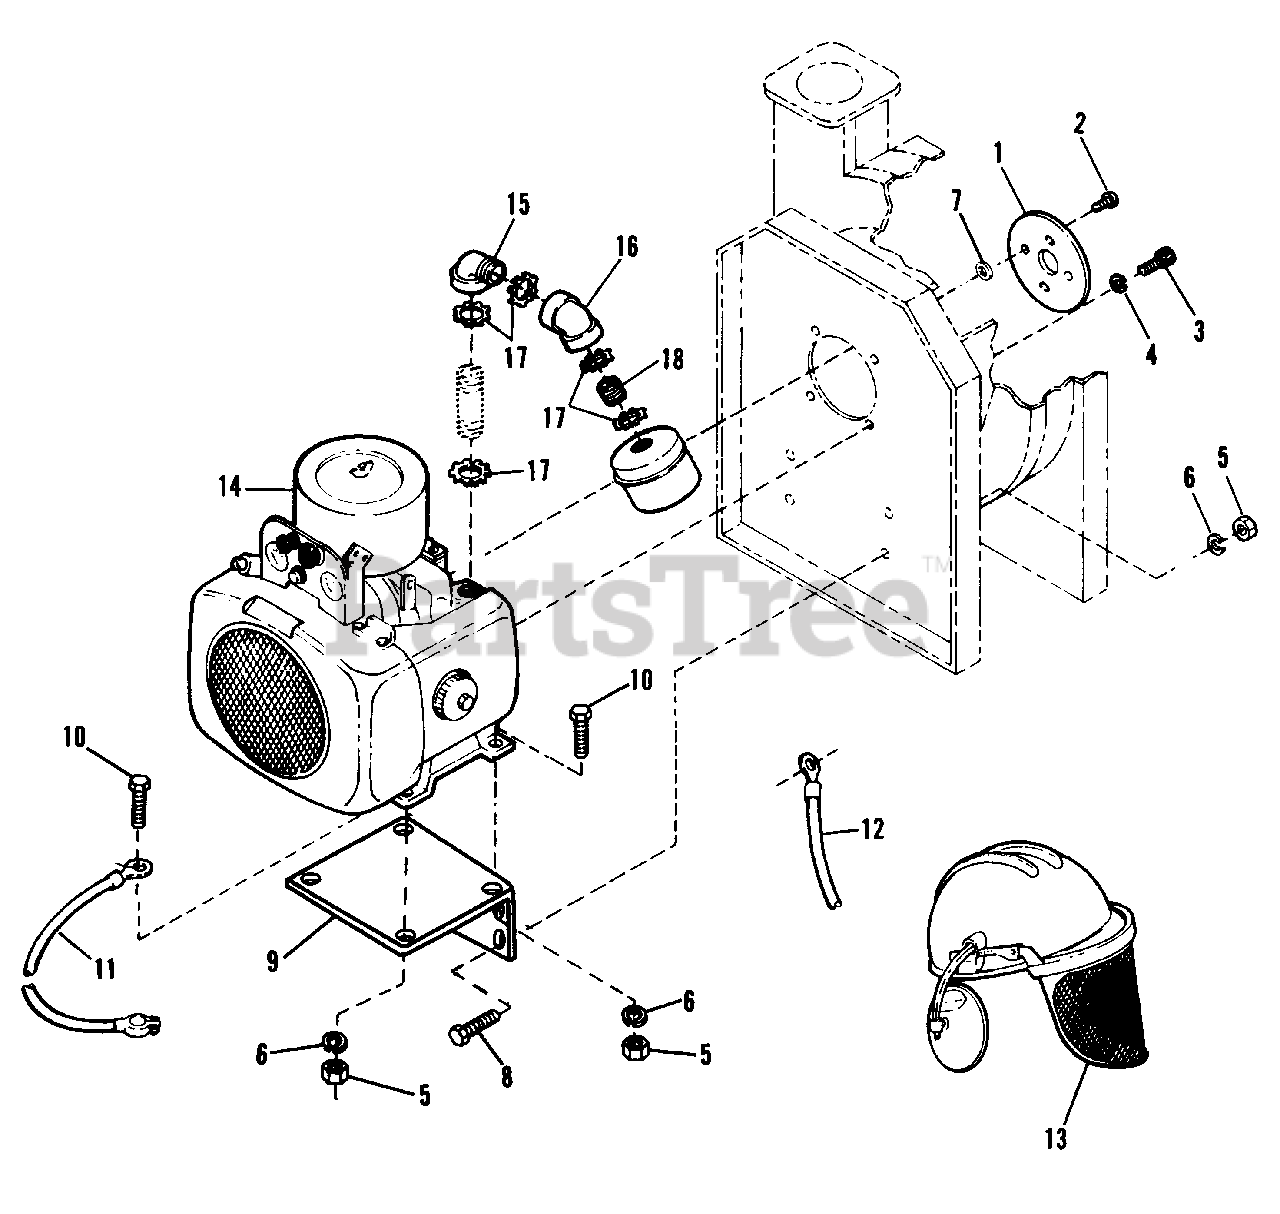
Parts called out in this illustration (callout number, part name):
1	GUARD, Seal
2	SCREW, Button Socket Hd., 3/8-16 x 3/4
3	CAPSCREW, Hex, 3/8-16 x 1-3/4
4	LOCKWASHER, 3/8
5	NUT, Hex, 7/16-14
6	LOCKWASHER, 7/16
7	WASHER, Plain, 13/32 x 7/8 x 5/64
8	CAPSCREW, Hex, 7/16-14 x 1
9	SUPPORT ASSY., Engine
10	CAPSCREW, Hex, 7/16-14 x 1-1/4
11	CABLE, Battery, Black, 30"
12	CABLE, Battery, Red, 41-1/2"
13	HARD HAT, Lower
14	ENGINE, Kohler, 20 HP
15	ELBOW, 1", 90ø
16	ELBOW, 1", 45ø
17	LOCKNUT, Conduit, 1"
18	NIPPLE, 1 x 1-1/2
